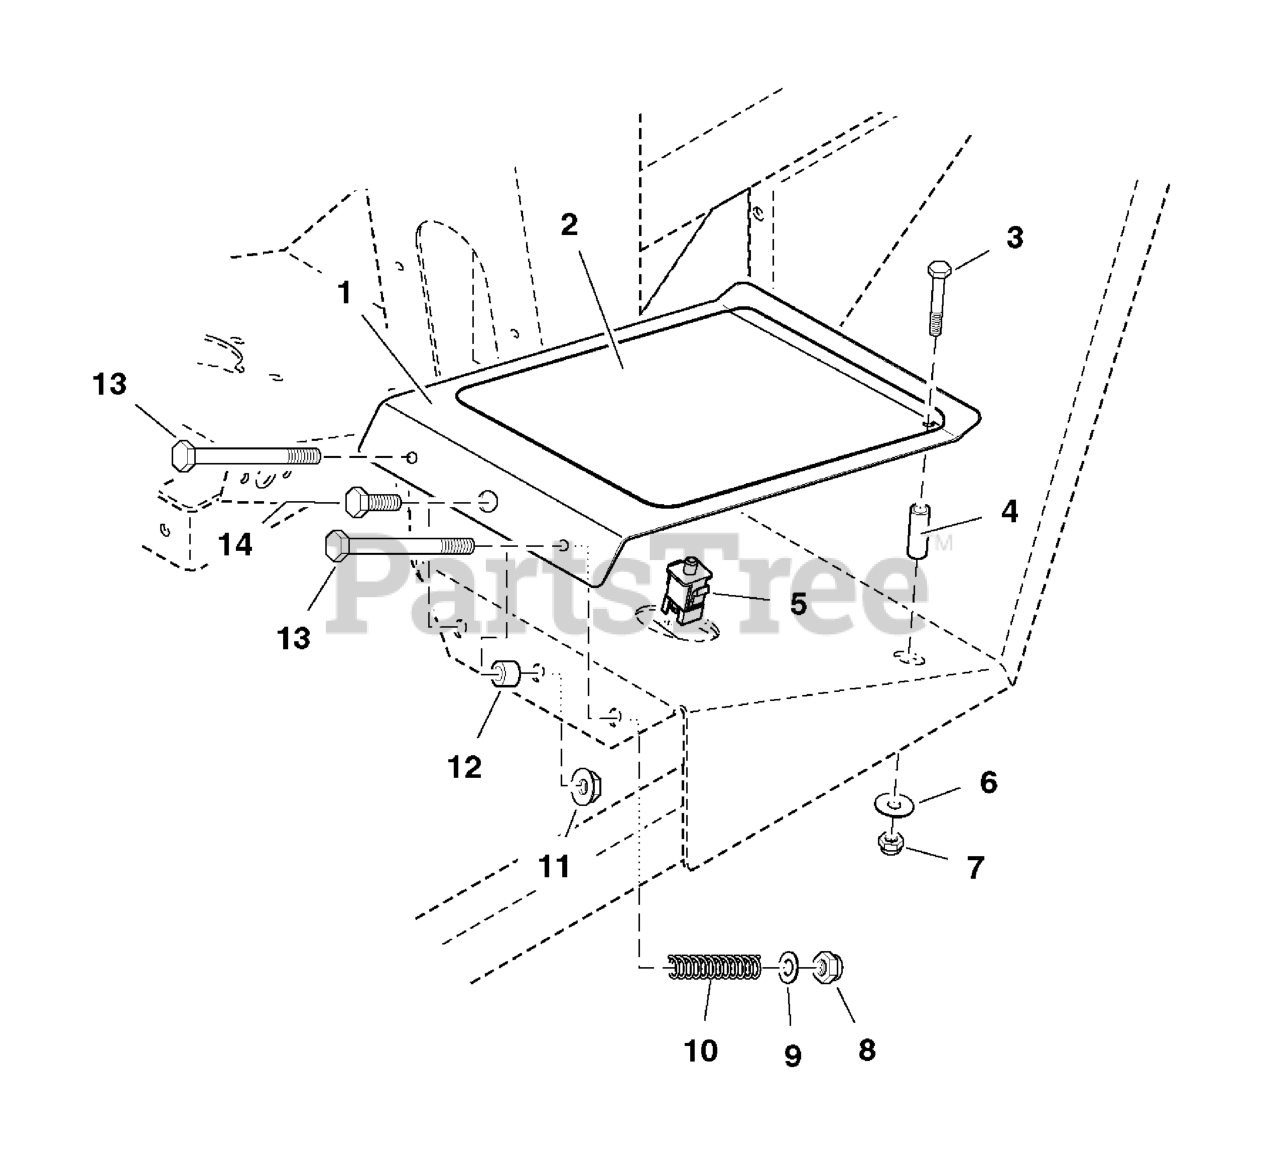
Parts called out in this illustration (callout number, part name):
1	OPERATOR PRESENCE PLATE
2	SAFETY WALK
3	BOLT, 5/16-18 x 2
4	BUSHING, Brass
5	SWITCH, Plunger, Snap-In, NO/NO
6	WASHER, 5/16" Fender
7	NUT, 5/16-18 Hex Nylon Lock
8	NUT, 3/8-16 HEX NYLON LOCK
9	WASHER, 3/8 SAE
10	SPRING, Compression
11	NUT, 3/8-16 Hex Serrated Flange
12	INSERT, Bearing
13	BOLT, 3/8-16 X 3-1/2" GD5 CZ
14	BOLT, 3/8-16 X 1" GD5 CZ
